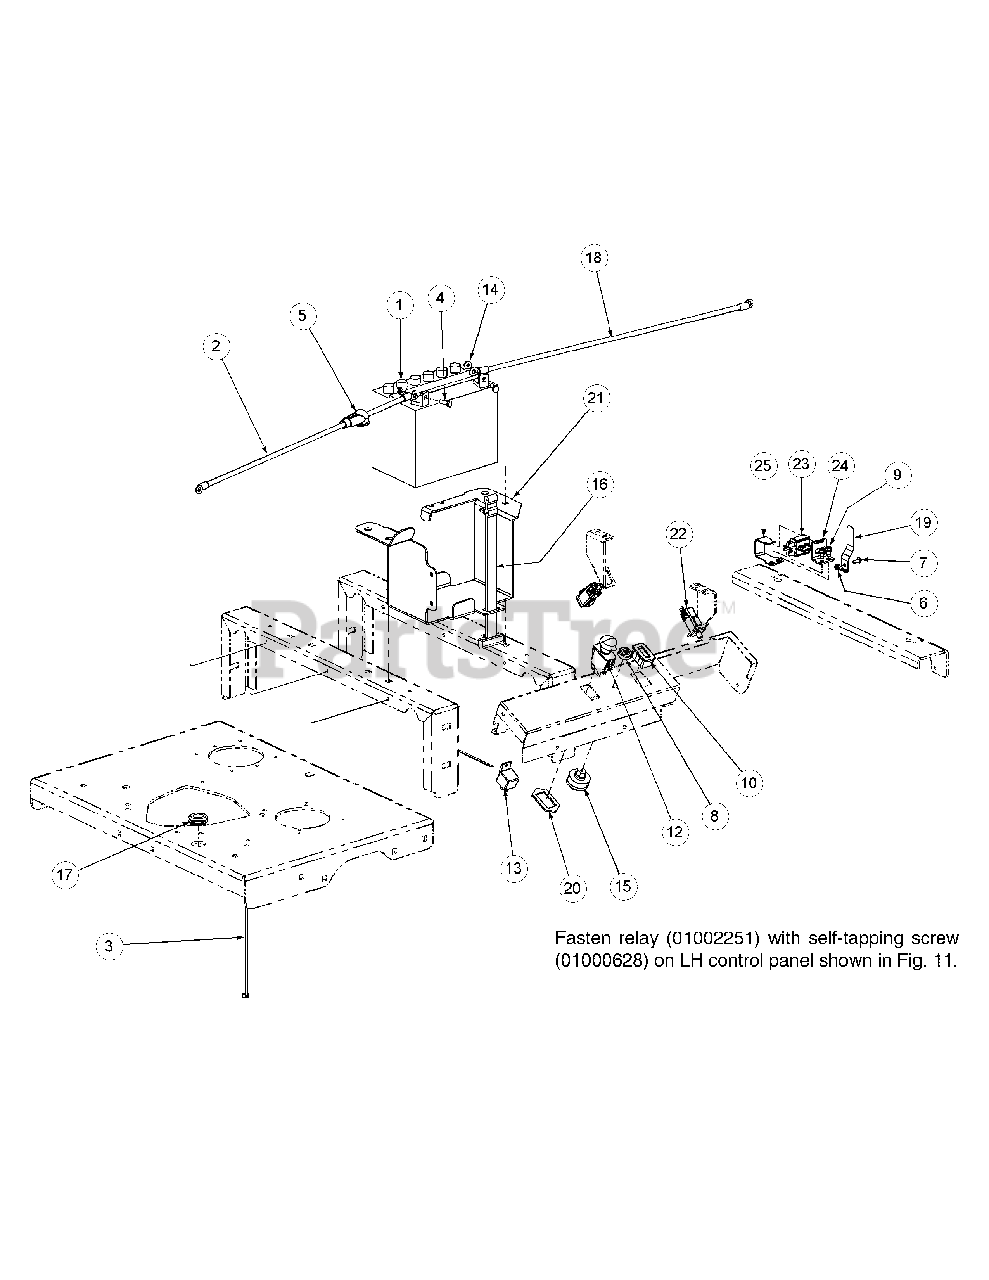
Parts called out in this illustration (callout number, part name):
1	Battery, 12V 225CCA 30 Min
2	Cable, Battery, Red, 42"
3	Tie, Cable, 3/16 x .05 x 7.4"
4	Screw, Hex, Cap, 1/4-20 x .75
5	Boot, 1" OD Rubber Battery-PST, Red
6	Lock Nut, Nylon Insert
7	Screw, Hex Washer, 10-32 x 1/2
8	Nut, W/Cap, 5/8-32 Ignition
9	Screw, TT, 1/4-20, 0.5, Hex Index Washer
10	Meter, Hour
12	Switch, Electric, PTO
13	Relay, 12V 40A
14	Lock Nut, 1/4-20
15	Switch, Ignition, 6 Pin
16	Strap, Battery
17	Grommet, .75 ID
18	Cable, Battery Red, 28"
19	Spring Retainer
20	Bracket, PTO Switch Retainer
21	Mount Bracket, Battery
22	Switch, Safety N.O./N.C.
23	Switch, Plunger
24	Bracket, Plunger Switch
25	Clamp, Plunger Switch
